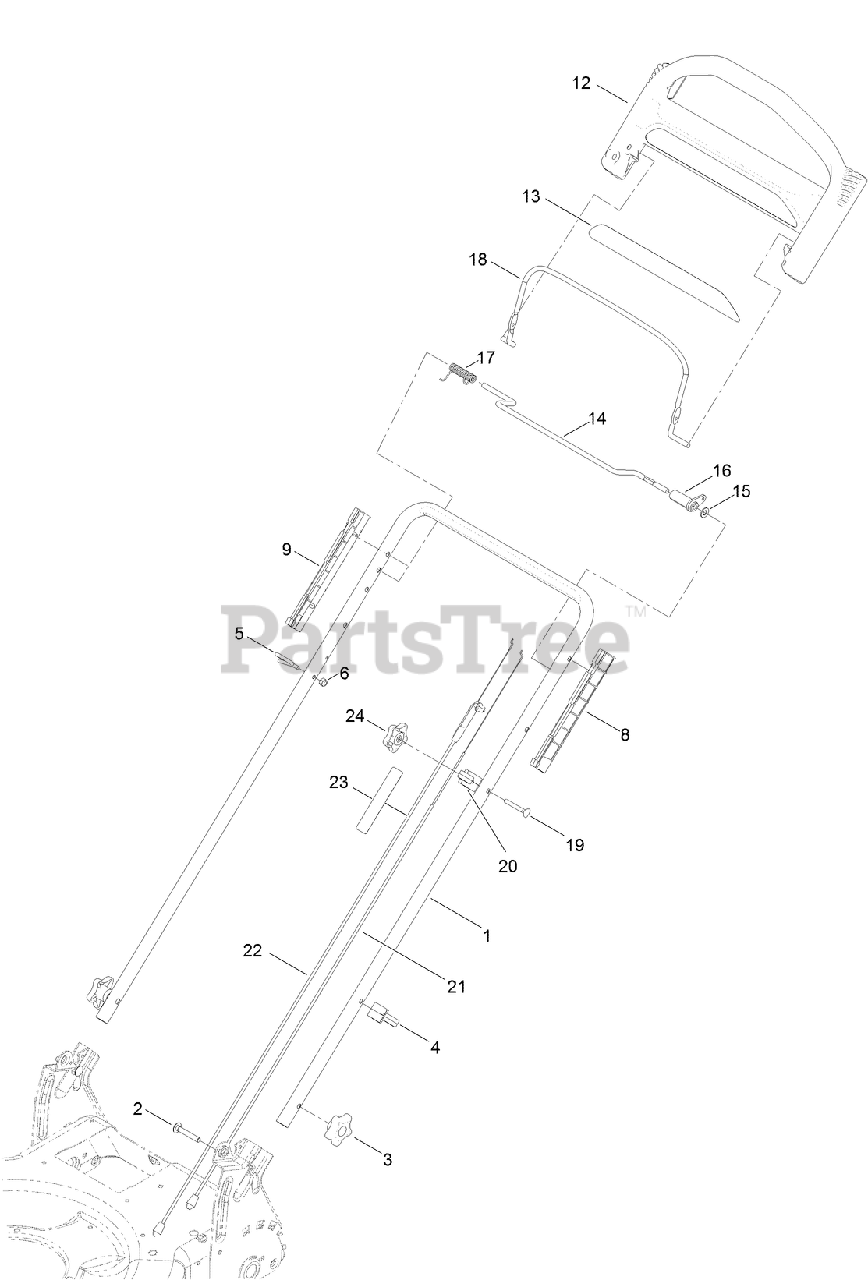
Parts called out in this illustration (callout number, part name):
2	Screw-CARR
3	KNOB-HANDLE
4	GUIDE-CABLE
5	GUIDE-ROPE
6	NUT-LOCK, NI
8	GUIDE-LH
9	GUIDE-RH
12	HANDLE-CONTROL
14	BAR-CONTROL, TRACTION
15	WASHER-PLAIN
16	LEVER-TRACTION
17	Spring-Torsion
18	Bail-Brake
19	SCREW
20	ANCHOR-CABLE
21	CABLE-TRACTION
22	CABLE-BRAKE
23	DECAL-TRACTION, ADJUST
24	KNOB-HANDLE, LOCKING
